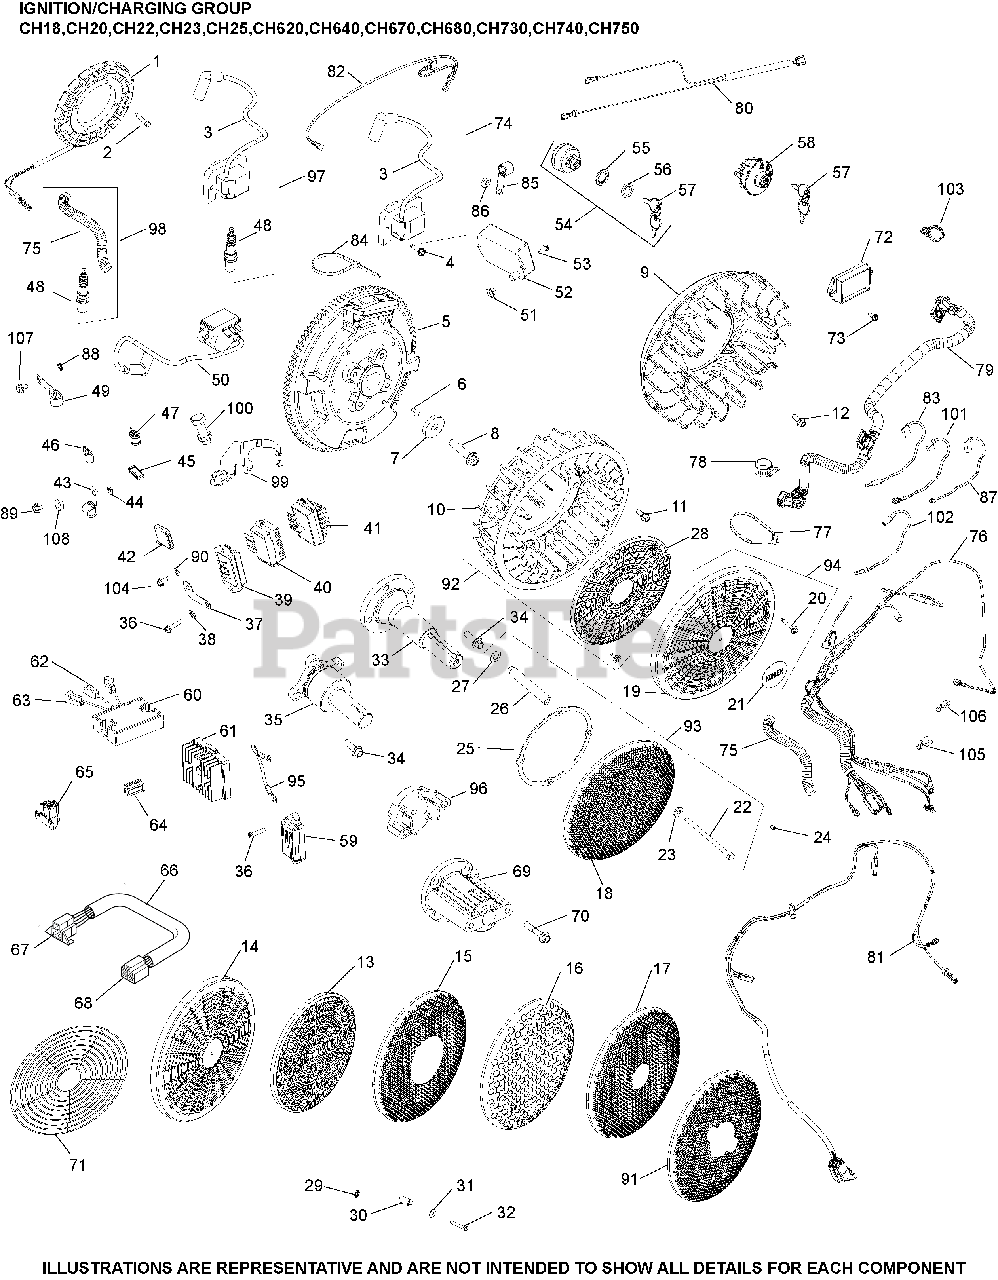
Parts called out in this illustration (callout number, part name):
1	STATOR KIT - USE 237878-S
2	SCREW, M5X0.8X25 - (#25086402S)
3	MODULE, IGNITION-USE 24 584 45-S
4	SCREW, FLG THD FRM M5X.8X20-(#25086399S)
5	FLYWHEEL, PAINTED-USE 24 025 55-S
6	KEY, 3/16" X 5/8"
7	WASHER, FLAT 13/32"
8	SCREW, FLG M10X1.5X45 - (#25086361S)
10	FAN USE 24 755 253-S
11	BOLT, SHOULDER
20	SCREW, SEMS DOG POINT
28	SCREEN,GRASS LOW PRFLE W/O HOLE
36	SCREW, HEX FLANGE HI-LO
36	SCREW, THREAD FORMING
37	BRACKET, GROUND STRAP USE 24 518 12-S
39	REG/RECT-15 AMP (KM)-USE 41 403 10-S
42	CONNECTOR, BODY (KM)-USE 25 155 41-S
48	PLUG, SPARK (PRO SERIES)
73	SCREW, WSH HD TAP #8-18X1/2"
76	HARNESS, WIRE-USE 24 176 171-S
95	LEAD, GROUND
